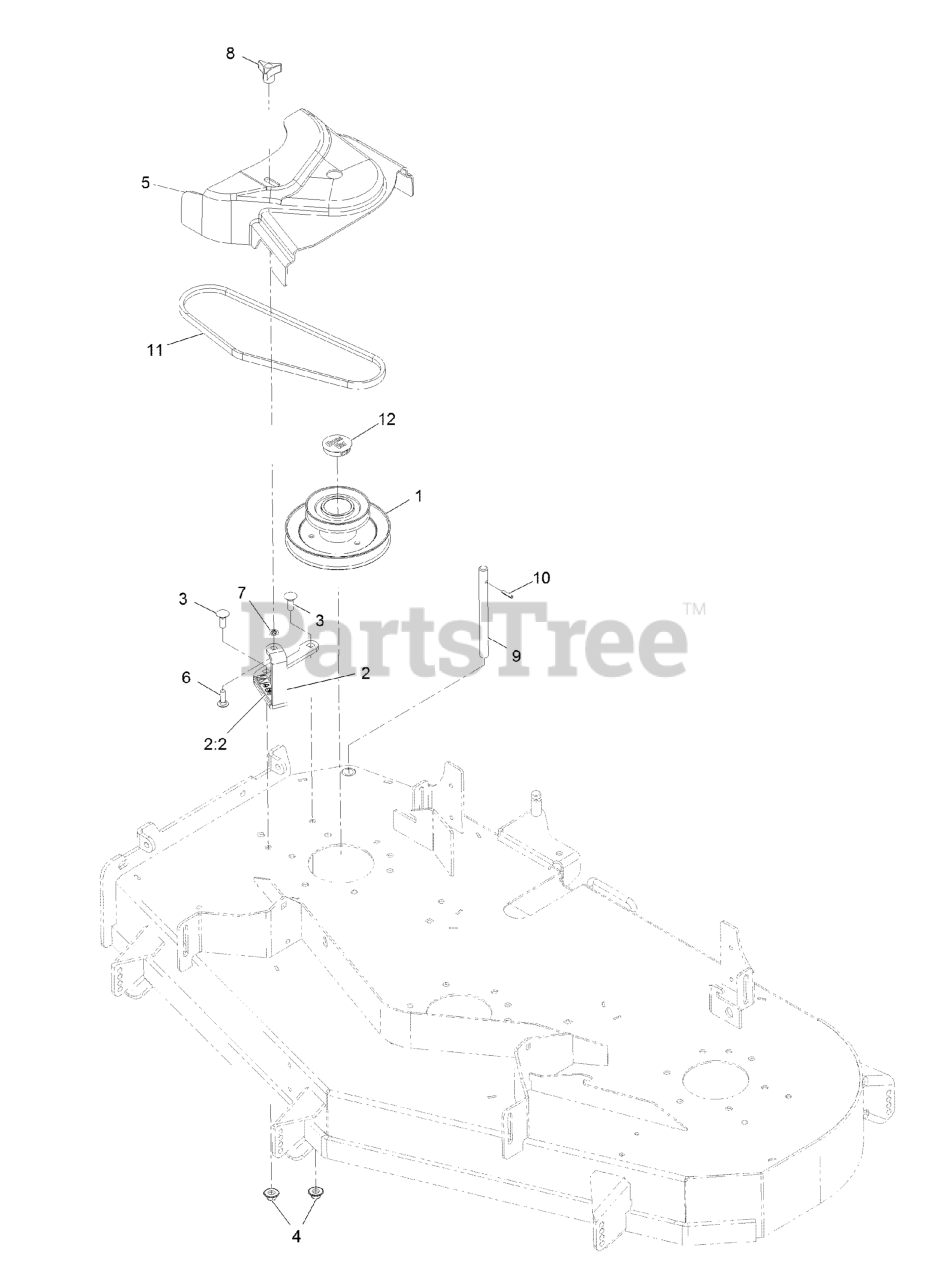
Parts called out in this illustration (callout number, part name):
1	JACKSHAFT-UV DRIVE 523
2	ASM-CVR BRKT W/DECAL
2:2	DECAL-DANGER
3	BOLT-CARR
4	Nut-Nyloc 3/8-16 Flg
5	COVER-BELT, UV 52 ENTRY
6	BOLT-CARR
7	RING-RETAINING, BOLT
8	KNOB-3 PRONG
9	SHAFT-CATCHER, GRASS
10	PIN-ROLL
11	BELT-BLOWER
12	PLUG, BLACK NYLON 1.75
